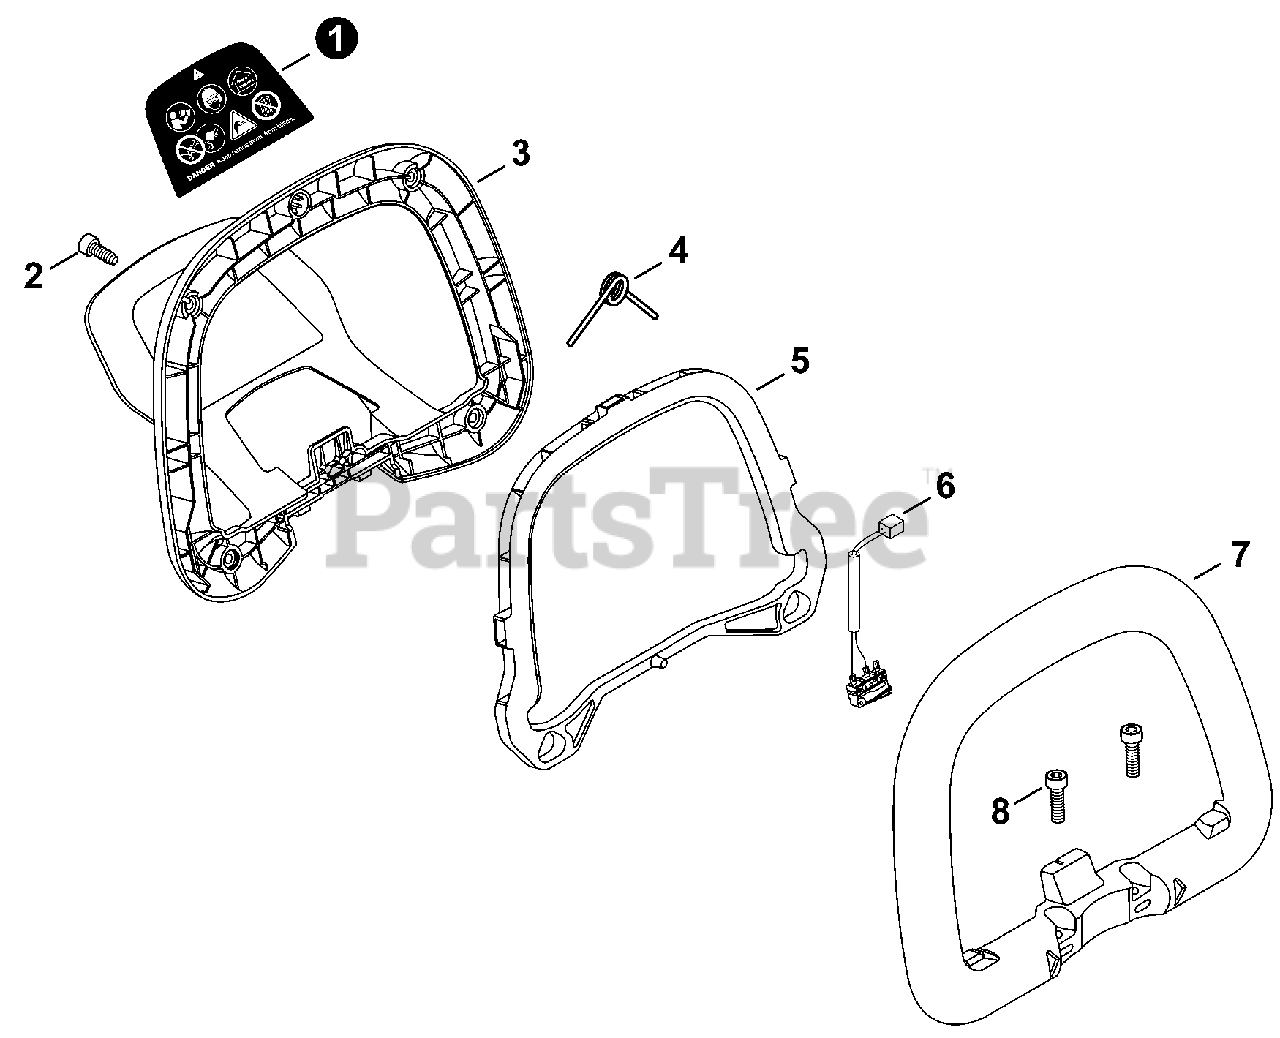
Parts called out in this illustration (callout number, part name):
1	LABEL, CAUTION
2	BOLT, TORX 4×16
3	HANDLE, SUPPORT
4	SPRING, TORSION
5	LEVER, LOCKOUT
6	SWITCH, HANDLE
7	COVER, HANDLE
8	BOLT, TORX 5×20
